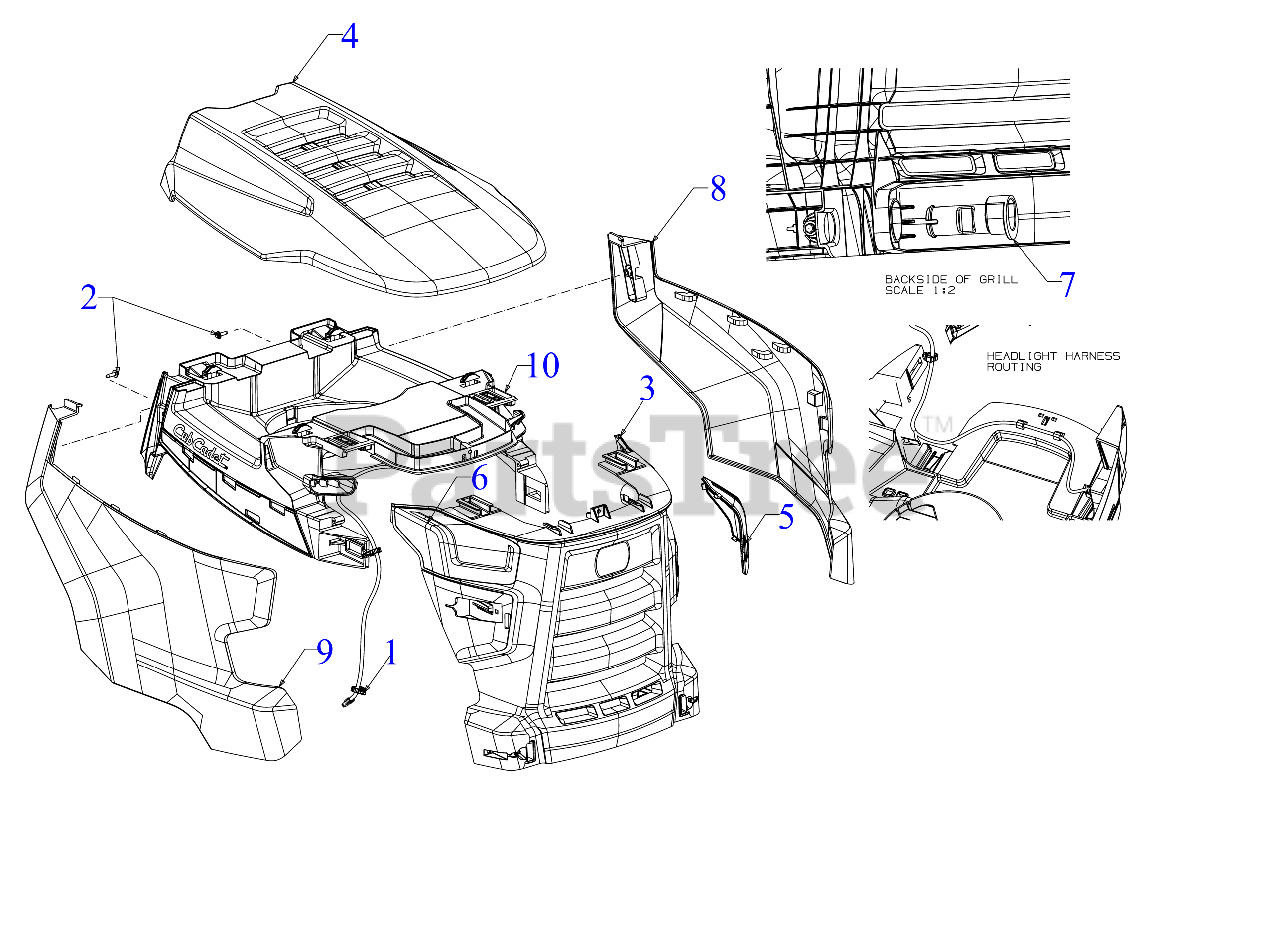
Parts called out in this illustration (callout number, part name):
1	HEADLIGHT HARNESS ASSEMBLY (W/LED)
2	SCREW 1/4-10 x .750
3	FRONT GRILLE (STYLE C)
4	HOOD TOP (YELLOW)
5	LED HEADLIGHT LENS (LH)
6	LED HEADLIGHT LENS (RH)
7	HOOD PIVOT PIN
8	SIDE PANEL (LH)
9	SIDE PANEL (RH)
10	PLENUM/HOOD FRAME
10	PLENUM/HOOD FRAME 679CC EFI
